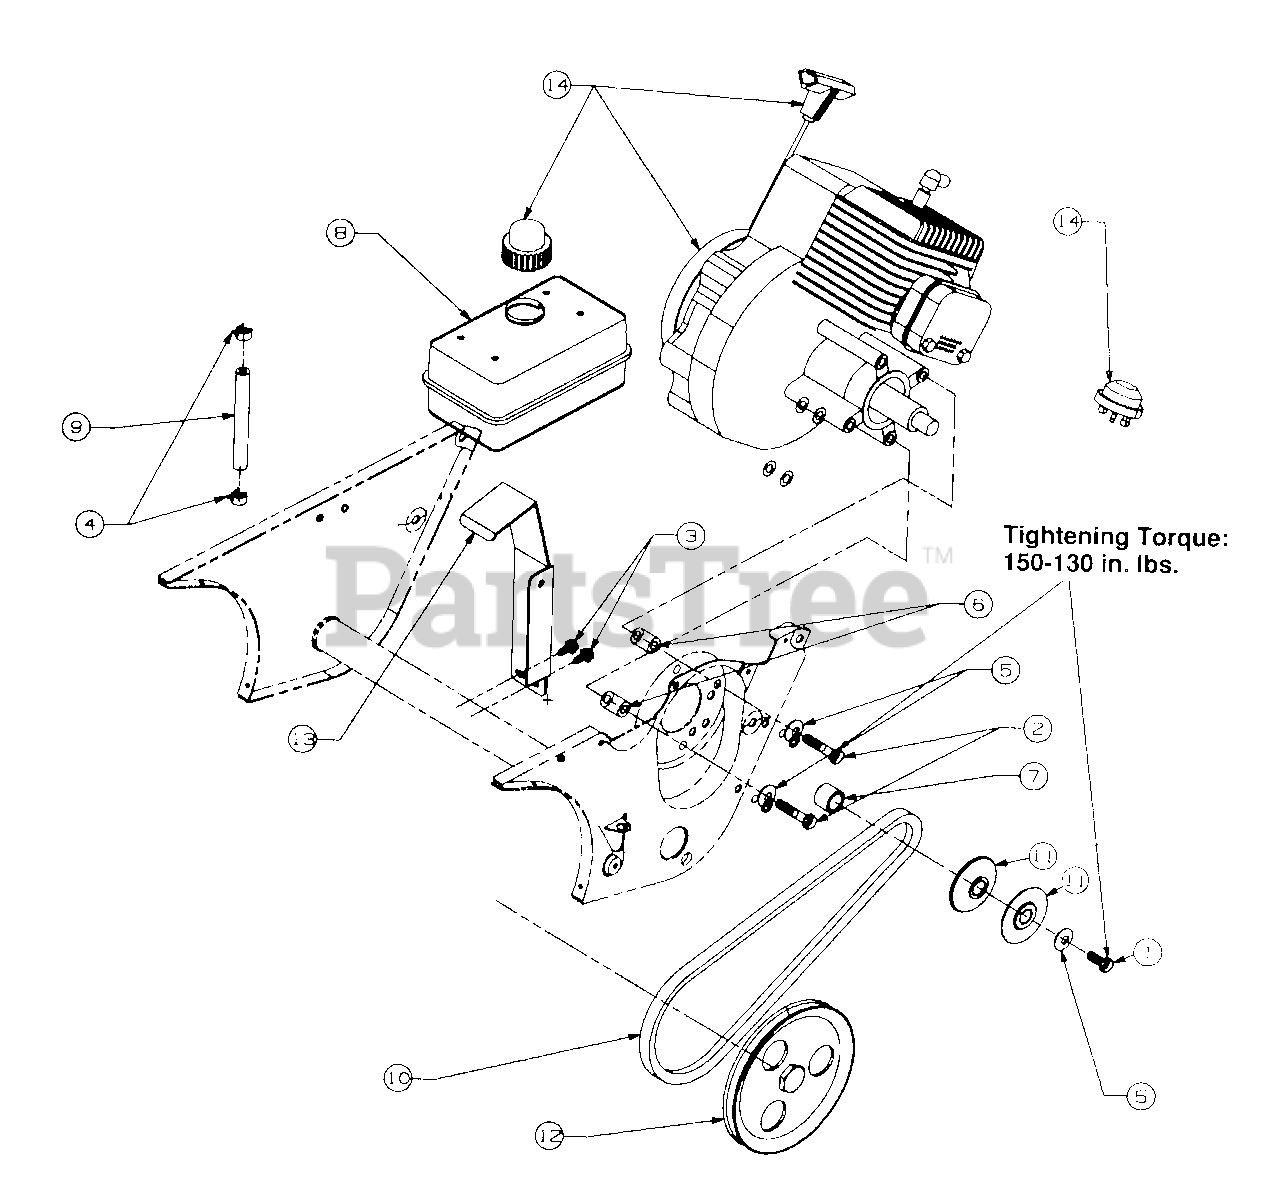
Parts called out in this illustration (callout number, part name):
1	Screw - Hex Cap
2	Screw - Hex Cap
3	Screw - Washer
4	Clamp - Hose
5	Washer - Bell
6	Spacer
7	Spacer
8	Tank - Fuel
9	Hose - Fuel 12"
10	V-Belt
11	V-Pulley Half
12	Pulley
